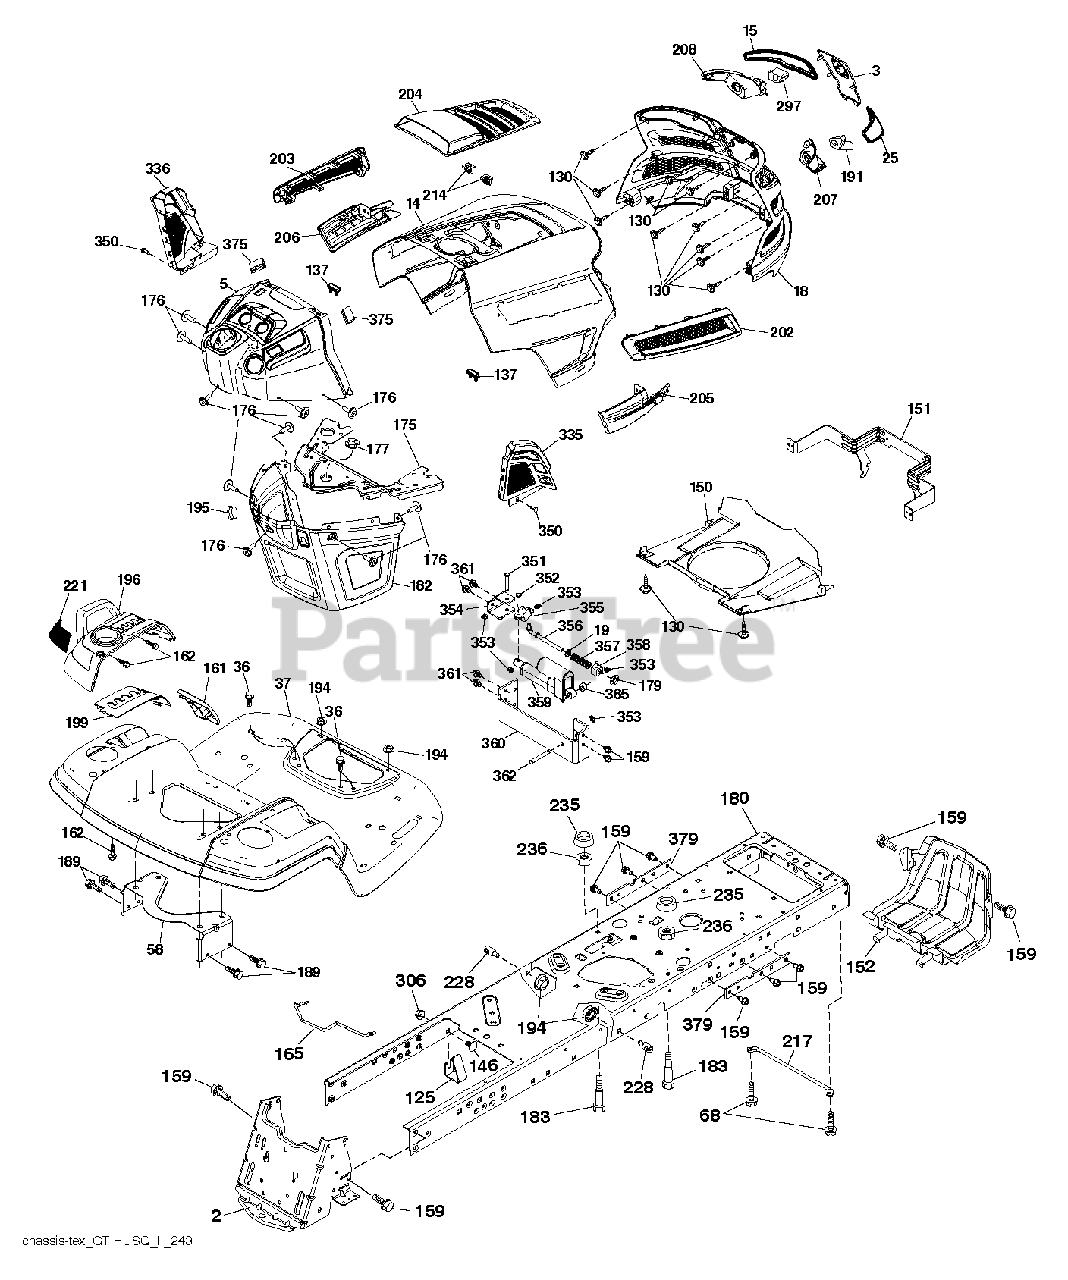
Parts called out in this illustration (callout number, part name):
2	DRAWBAR.STGT
3	APPLIQUE.SUBASM.GT.HUSQ.II
5	DASH.TEX.GT2.UPPER
14	HOOD.ASM.HUSQVARNA.GT.TEX.ORAN
15	LENS.HEADLIGHT.LH.GTII.2011
18	GRILLE SUBASM.GT.II.LOW.HDLGHT
19	WASHER
25	LENS.HEADLIGHT.RH.GTII.2011
36	SCREW 5/16"
37	FENDER.PNT.TX.GT.CH/FW/DL.HUSQ
58	BRKT.SUPPORT.FNDR/TANK
68	SCR 5/16-18 X 1/2 SELFTAP ZN
125	CLIP.FUEL.LINE
130	SCREW.#10 X 0.750.BOS
137	BUMPER DASH
146	BOLT.RDHD.SHT.SQNK.3/8-16X5/8
150	AIR.DUCT.GTV.BLACK
151	BRACKET.PIVOT.HOOD.GT.HUSQ.II
152	SHIELD.BROWNING.PNT.GT.V2
159	SCREW, 3/8-16X3/4
161	CONSOLE.WINDOW.FUEL.HUSQ.GT
162	SCREW.HI-LO.CONSOLE
165	SUPPORT.TANK.REAR.B/TE
175	PLATE.CROSSMEMBER.HUSQ
176	SCREW.#10-24X5/8.RN.QU
177	BUSHING STEERING
180	CHASSIS.TEX.BOLTED
182	DASH.LOWER.COMMON.12V.ADAPTOR
183	BOLT.5/16-18X1-1/4 FULL THD
189	SCREW
191	INSERT.REFLECTIVE.RH.HUSQ.GTII
194	NUT LOCK HEX FLANGE 5/16-18
195	PLUG.HOLE.DASH.LOWER.12V.BLK
196	CONSOLE.ASM.DECKLIFT.HUSQGT.DL
199	PLATE.DECK.LIFT.HUSQVARNA.GT
202	VENT.SIDE.RH.GT.HUSQ.II.
203	VENT.SIDE.LH.GT.HUSQ.II.498
204	VENT.TOP.HUSQ.GT2
205	SIDE.TRIM.RH.GT.HUSQ.II
206	SIDE.TRIM.LH.GT.HUSQ.II.GRAY
207	HEADLIGHT.CUP.BEZEL.HUS.GT2.RH
208	HEADLIGHT.CUP.BEZEL.HUS.GT2.LH
214	CLIP.RETAINER.TINNER.
217	ROD.PIVOT.HOOD
221	REFLECTOR.LH.TEX GT HU
228	STUD.FASTNER.W/ANTI-ROTATE
235	SPACER FENDER
236	NUT.CENTERLOCK.5/16-
297	INSERT.REFLECTIVE.LH.HUSQ.GTII
306	NUT LOCK FLG 3/8-16 UNC
335	COVER.LOWER.DASH.RH.BLACK
336	COVER-LH.LOWER.DASH.GT2.BLACK
350	CLIP.X-MAS.TREE
351	PIN.CLEVIS.375X2.125
352	PIN.CLEVIS.(.375 X 1.25)
353	CLIP RETAINER
354	SUPPORT.BELLCRANK
355	BELLCRANK.PIVOT.LOCK.DIFF
356	LINK.LOCK.DIFF
357	SPRING.COMPRESSION
358	GUIDE.SWIVEL
359	ACTUATOR.ELECTRIC
360	BRACKET.ACUATOR
361	SCREW LT.3/8-46X5/8
362	PIN.CLEVIS.(.375 X 2.42)
365	SPACER.NYLON.75" X .4375
375	BUMPER CLIP-ON. DASH 1"
379	CHASSIS.PLATE.REINFORCEMNT.431
